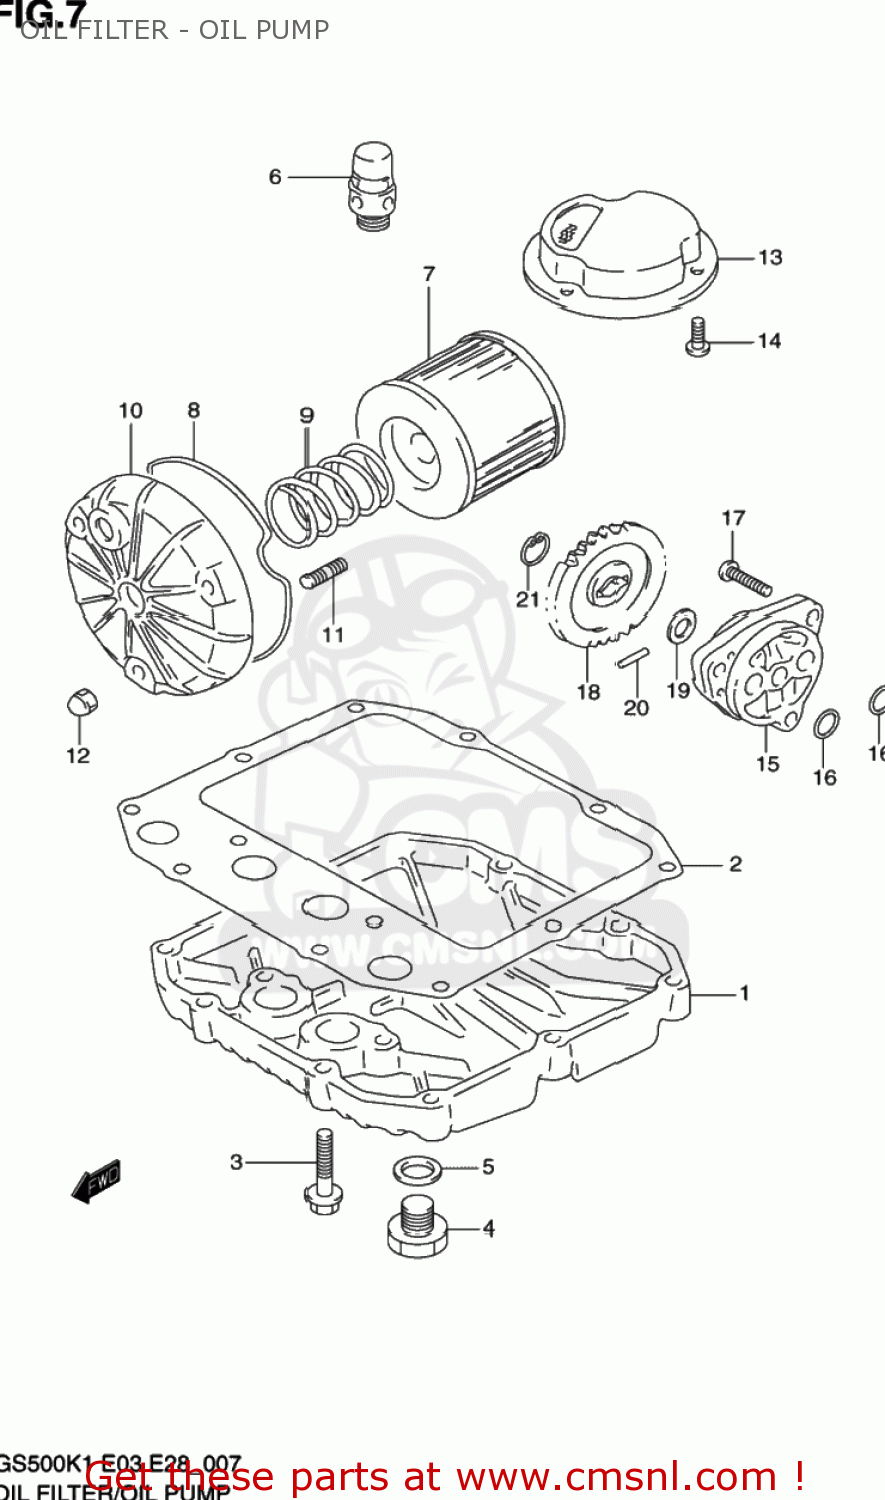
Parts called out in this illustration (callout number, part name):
1	PAN,OIL
2	GASKET,OIL PAN(ASB) (NAS)
3	BOLT
4	PLUG(14X12)
5	GASKET(13.8X18.8X4.8) (NAS)
6	REGULATOR,ENGINE OIL(6.5K)
7	FILTER ASSY,ENGINE OIL
8	O RING,OIL FILTER CHAMBER CAP
9	SPRING
10	CAP,OIL FILTER
11	STUD 6X20
12	NUT
13	STRAINER,ENGINE OIL
14	BOLT
15	PUMP ASSY,ENGINE OIL
16	O RING(D:1.9,ID:13)
17	SCREW
18	GEAR,OIL PUMP DRIVEN
19	SHIM(10X18X0.5)
20	PIN(4X15.8)
21	CIRCLIP,10MM
